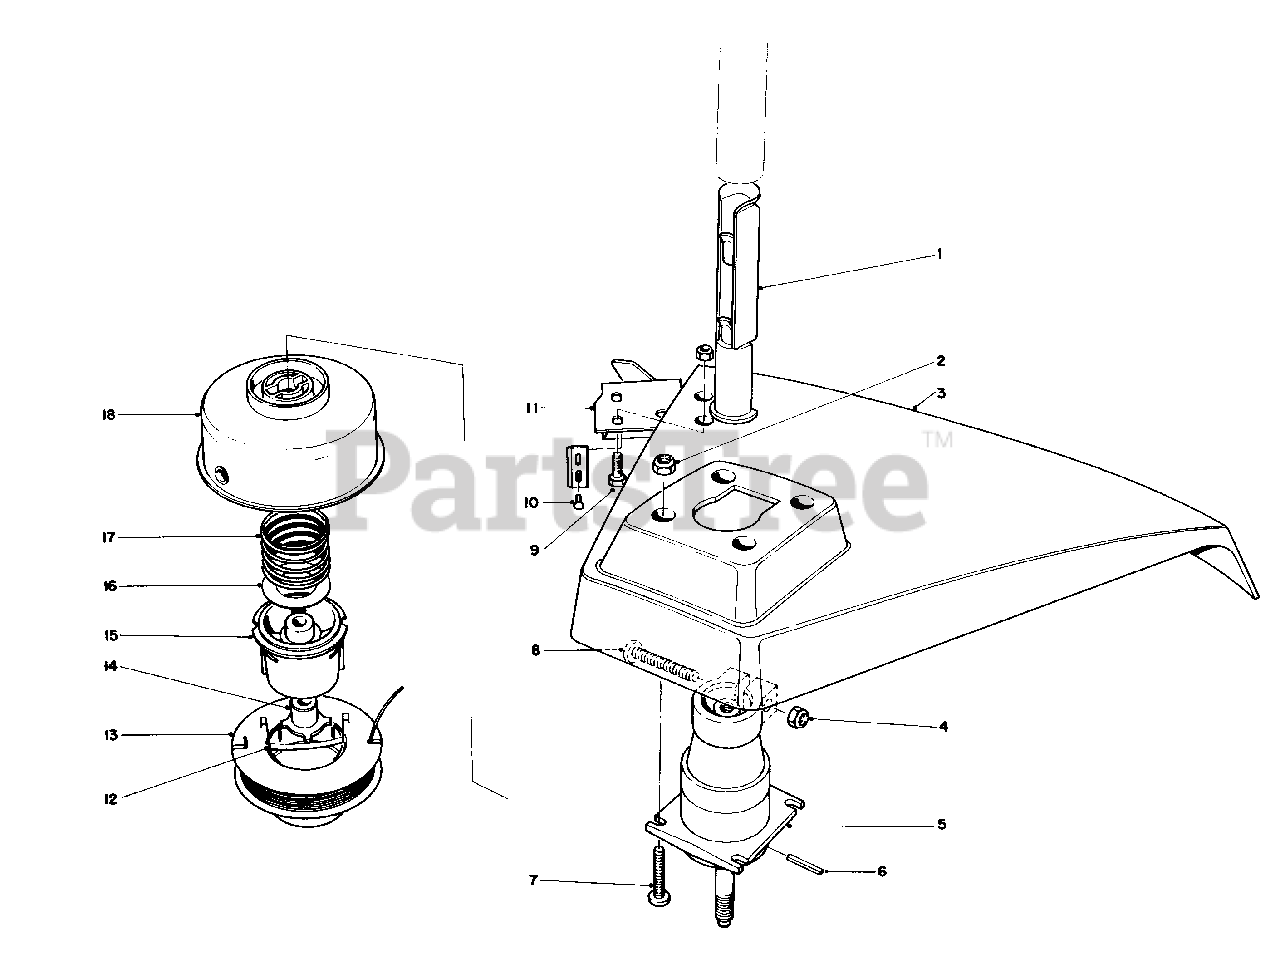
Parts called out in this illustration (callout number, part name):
1	Insert-Pole End
2	Locknut
3	Shield 14"
5	Bearing Housing Assembly
6	Pin Coil
7	Cross Recess Pan Hd. Machine Screw
8	Slotted Pan Hd. Machine Screw
9	Hex Washer Hd. Machine Screw
10	Pop Rivet
11	Knife Blade Assembly (Incl. Ref. #10)
12	Saddle-Spool Cap
13	Prewound Spool (.080)
15	Spool Core
17	Spring-Compression
18	Drum & Eyelet Assembly
